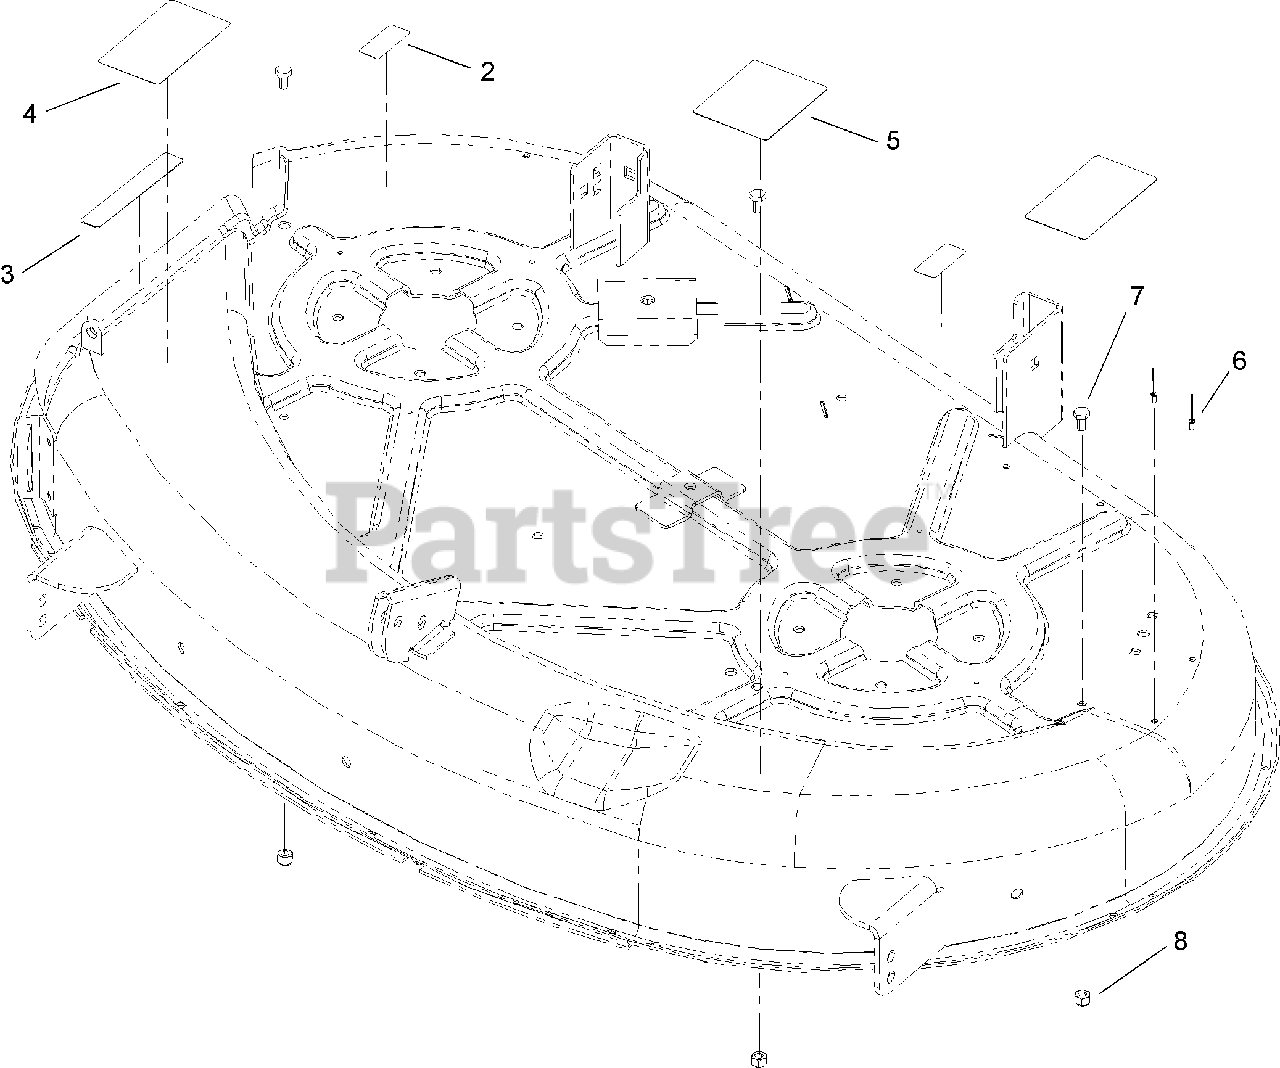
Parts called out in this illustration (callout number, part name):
2	DECAL-DANGER, PULLEY
3	DECAL-DANGER
4	DECAL-DANGER
5	DECAL-ROUTING, BELT
6	RIVET-POP
7	SCREW-HH
8	NUT-LOCK, NI
